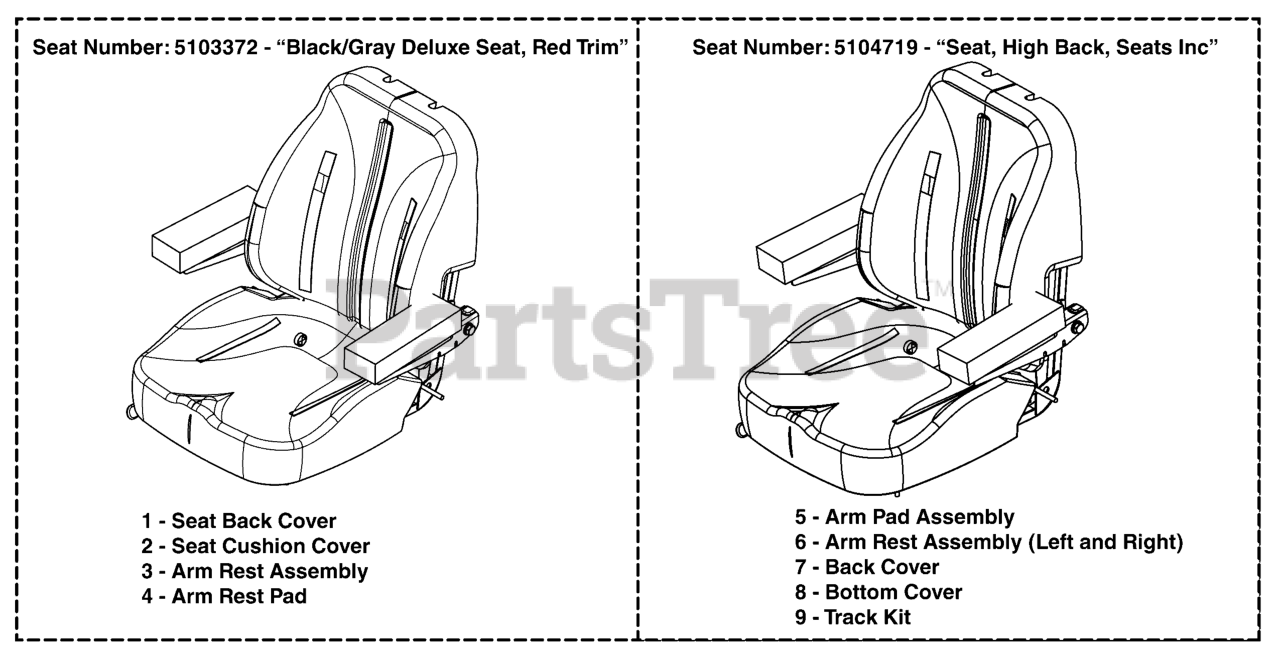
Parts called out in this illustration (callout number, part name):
1	COVER, SEAT BACK, EVC, SEATS INC
2	COVER, CUSHION, EVC, SEATS INC
3	ARM REST ASSEMBLY
4	ARM REST PAD
5	ARM PAD ASSEMBLY
6	ARM REST ASSEMBLY (LEFT AND RIGHT)
7	BACK COVER
8	CUSHION COVER
9	TRACK KIT
